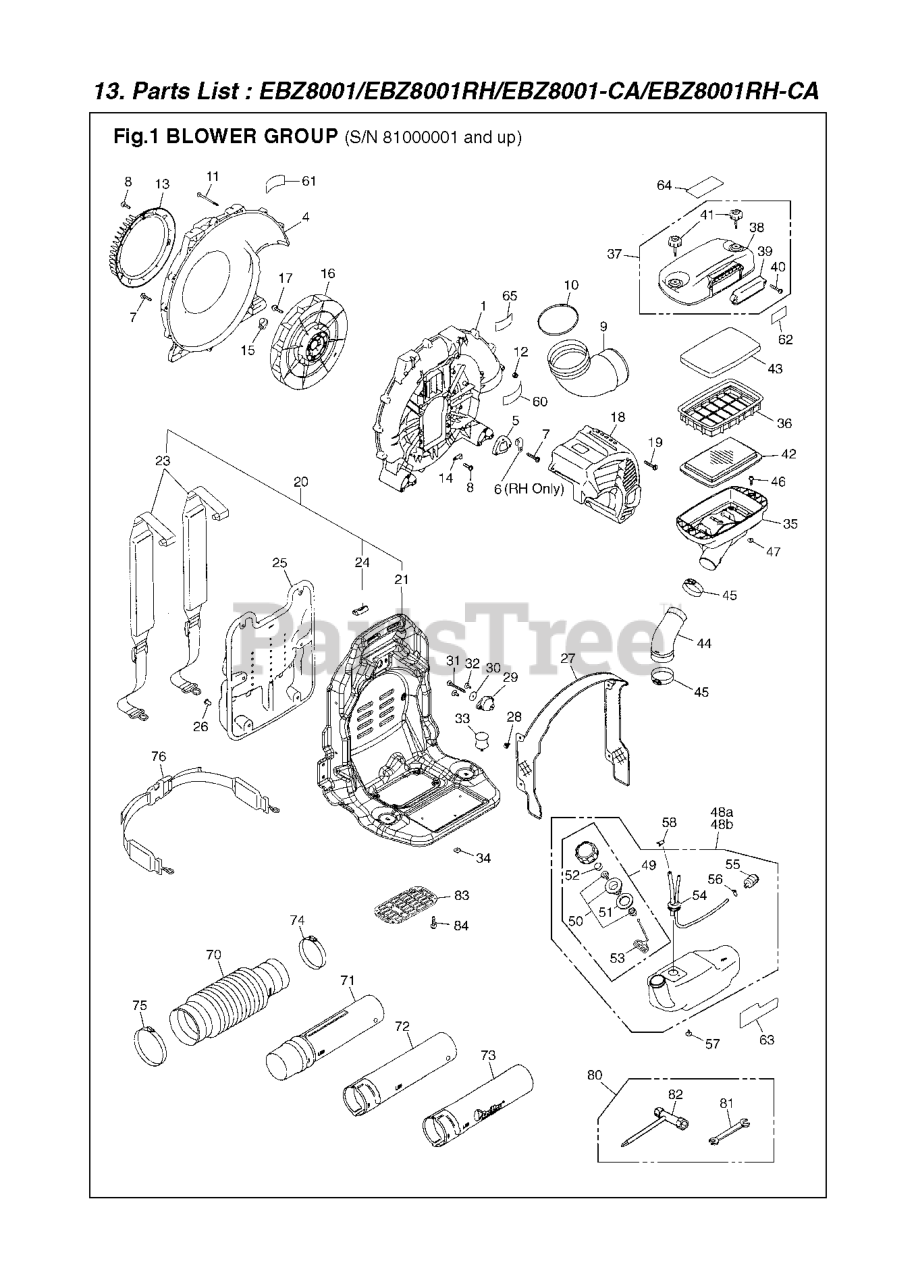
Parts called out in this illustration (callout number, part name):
1	VOLUTE CASE
9	ELBOW
10	0-RING
13	COVER (FUNNEL)
14	CLAMP
17	BOLT
18	COVER.ENGINE
20	FRAME (RPLS 848L5M3500)
21	FRAME EBZ8001(R-848L583513,14)
23	BAND ASSY (RPLS 848L583611)
24	CLIP
25	PAD
26	CLIP
28	CLIP
29	DAMPER UPPER
30	WASHER
31	BOLT
33	DAMPER
37	COVER ASSY
41	KNOB BOLT-RED
42	ELEMENT
43	ELEMENT
45	CLAMP
48A	TANK-A***
49	ASSY FUEL CAP
50	HOLDER-A
54	PIPE C
55	FILTER ASSY
56	CLIP
58	CLIP
60	LABEL.CAUTION
61	LABEL, NET
62	LABEL EBZ8001
63	LABEL,TANK
70	HOSE ALT 848L6565A0
71	SWIVEL JOINT
73	PIPE END (RPLS 848L5865E0)
74	CLAMP
75	CLAMP
76	BAND ASSY (RPLS 848L583620)
80	TOOL-SET
82	SOCKET
